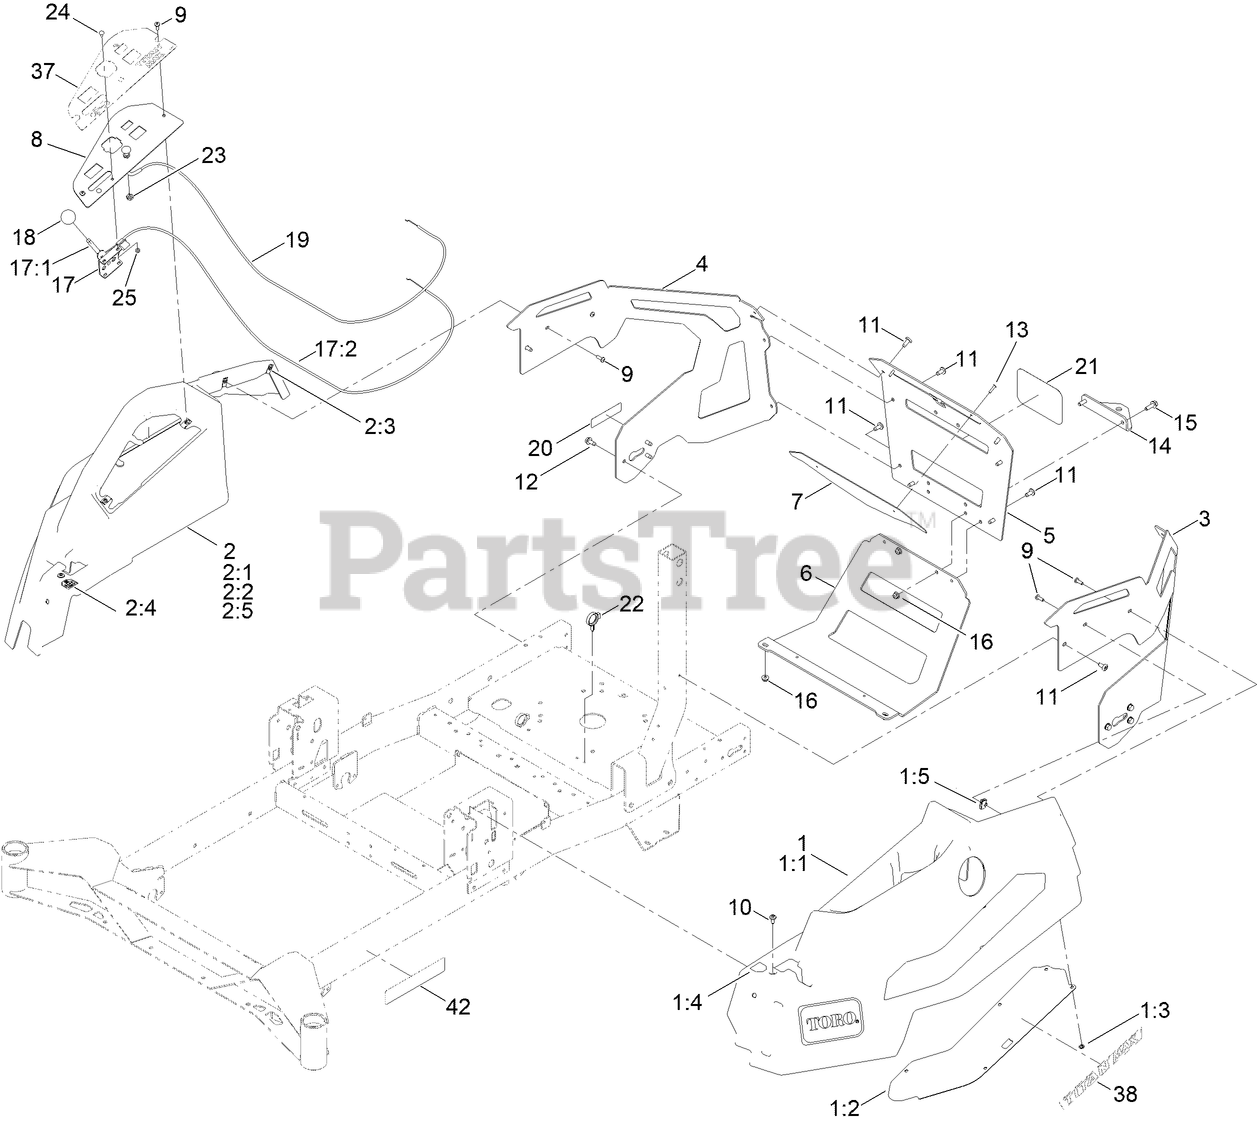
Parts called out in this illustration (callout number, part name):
1	TITAN MAX LH POD ASM
1:1	POD-LH
1:2	PLATE-POD, LH
1:3	NUT-PUSH
1:4	DECAL-CONTROL LEVER, LH
2	TITAN MAX RH POD ASM
2:1	POD-RH
2:2	PLATE-POD, RH
2:4	DECAL-CONTROL LEVER, RH
2:5	NUT-PUSH
3	GUARD-ENGINE, LH
4	GUARD-ENGINE, RH
5	GUARD-ENGINE
6	GUARD-MUFFLER
7	PLATE-BACKER
8	PANEL-CONTROL
9	SCREW-PH
10	SCREW-SHOULDER
12	SCREW-HWHTF
13	RIVET-TRIFOLD
14	BRACKET-HITCH
15	SCREW-HHF
16	NUT-HF
17	THROTTLE CONTROL ASM
17:1	LEVER-THROTTLE
18	KNOB-BALL
19	CABLE-CHOKE CONTROL
20	DECAL-SPARK ARRESTER
22	CLAMP-HOSE
23	NUT-HJ
24	BOLT-CARR
25	NUT-LOCK, NI
37	DECAL-PANEL, CONTROL
38	DECAL-TITAN MAX
42	DECAL-HAVOC
